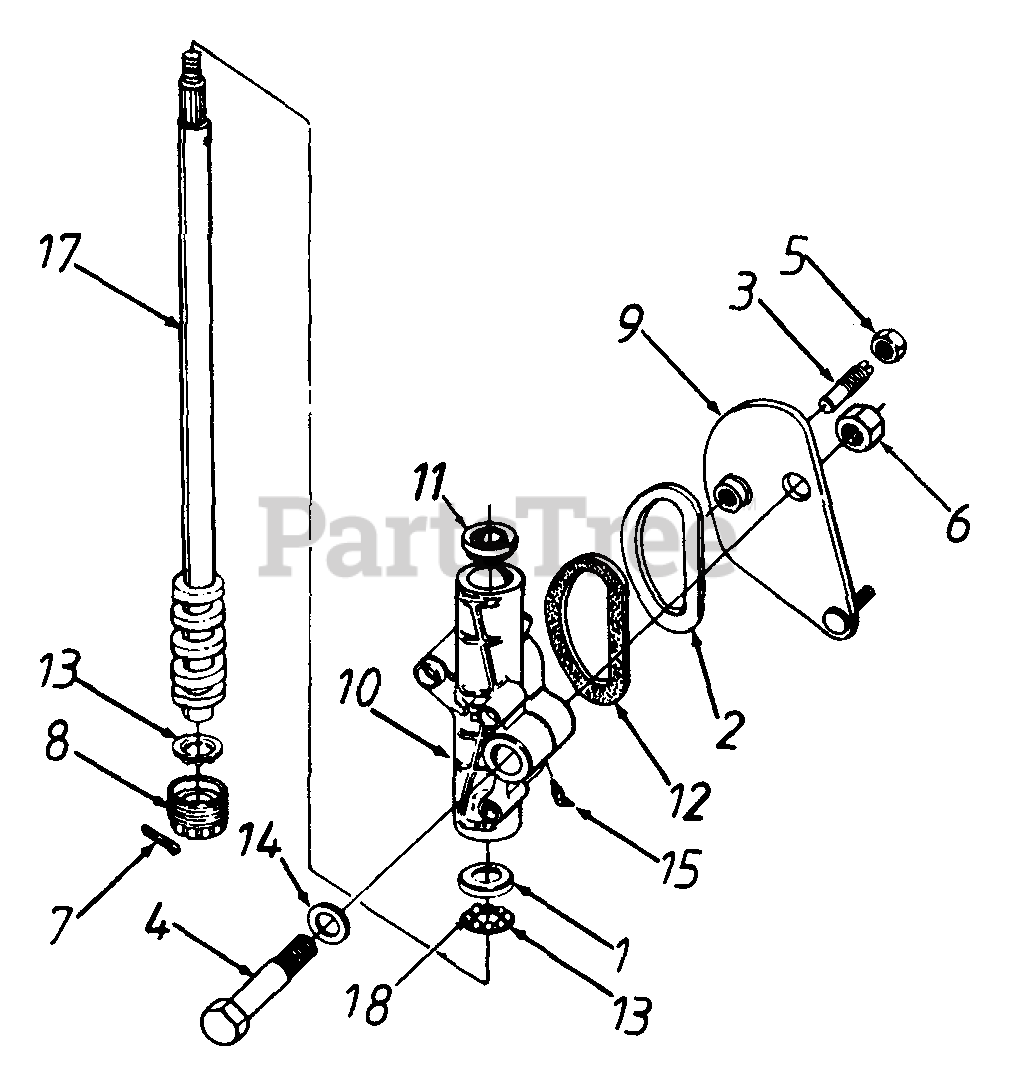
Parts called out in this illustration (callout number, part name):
1	Bearing Cup
2	Seal Retainer
3	Cam Follower
5	Hex Jam Nut 9/16-18 Thd.
6	Hex Crown L-Nut 5/8-18 Thd.
7	Cotter Pin 1/8" Dia.
8	Adjustment Plug Ass'y.
9	Steering Arm Ass'y.
10	Steering Hsg. Bushing Ass'y.
12	Seal
13	Ball Retainer
14	Fl-Wash. .781" I.D. x 1.25" O.D.
15	Grease Fitting
17	Steering Shaft Ass'y.
18	Ball Bearing
